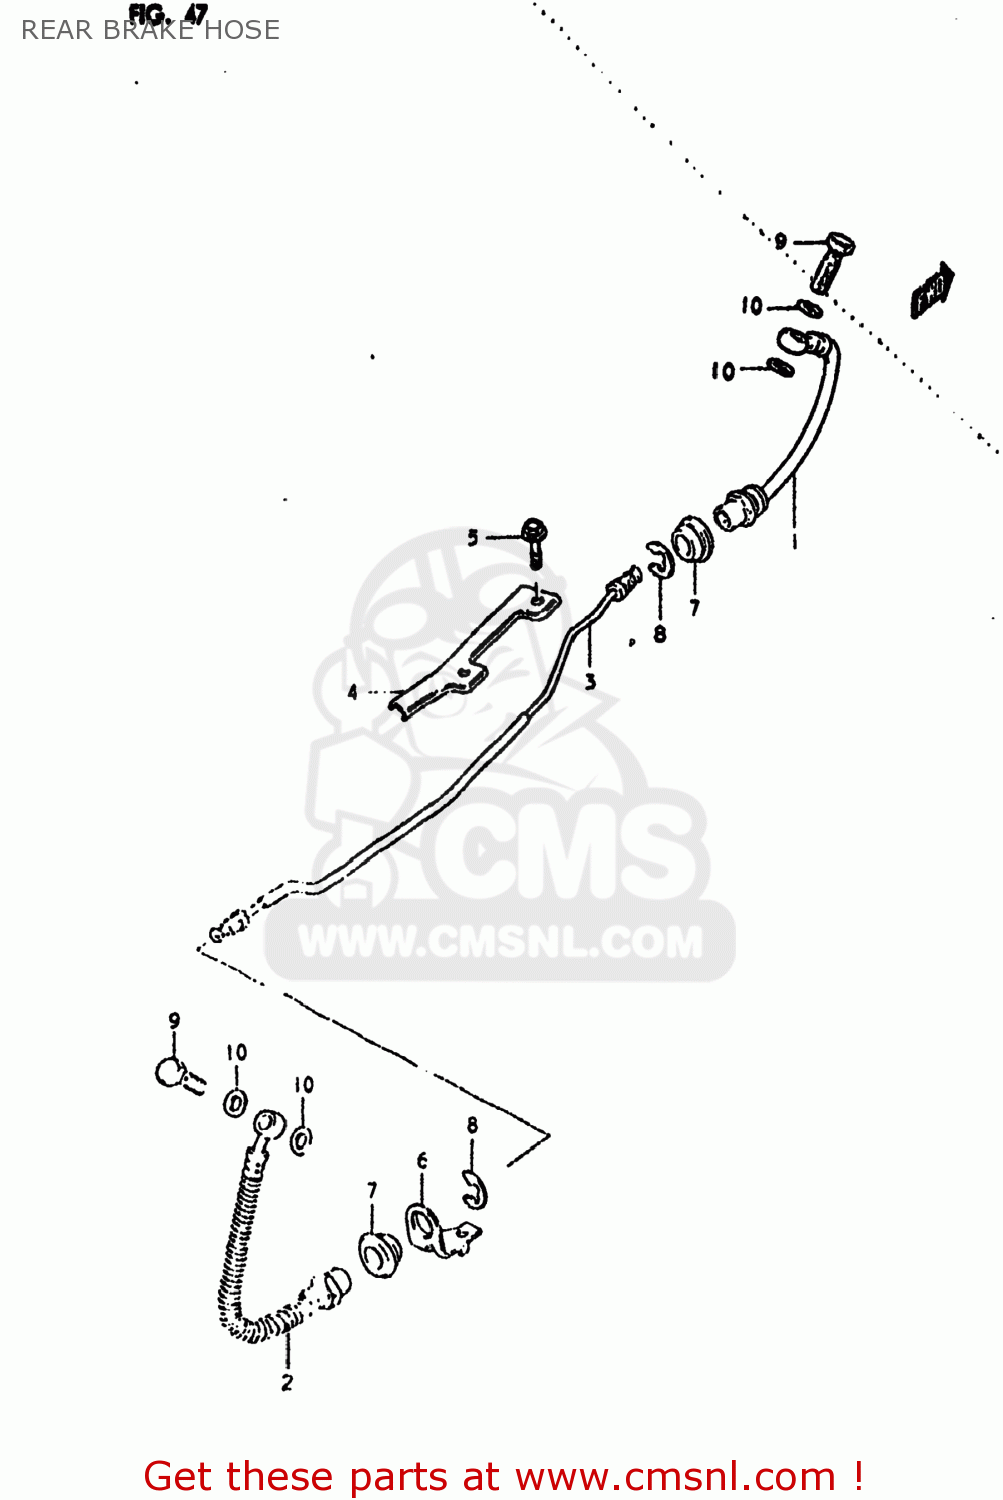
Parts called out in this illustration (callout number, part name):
1	HOSE,REAR BRAKE NO.1
2	HOSE,RR BRAKE NO.2
3	PIPE,REAR BRAKE
4	COVER,REAR BRAKE PIPE
5	BOLT
6	GUIDE,BRAKE HOSE
7	GROMMET,BRAKE HOSE GUIDE
8	E RING
9	BOLT,UNION
10	WASHER
